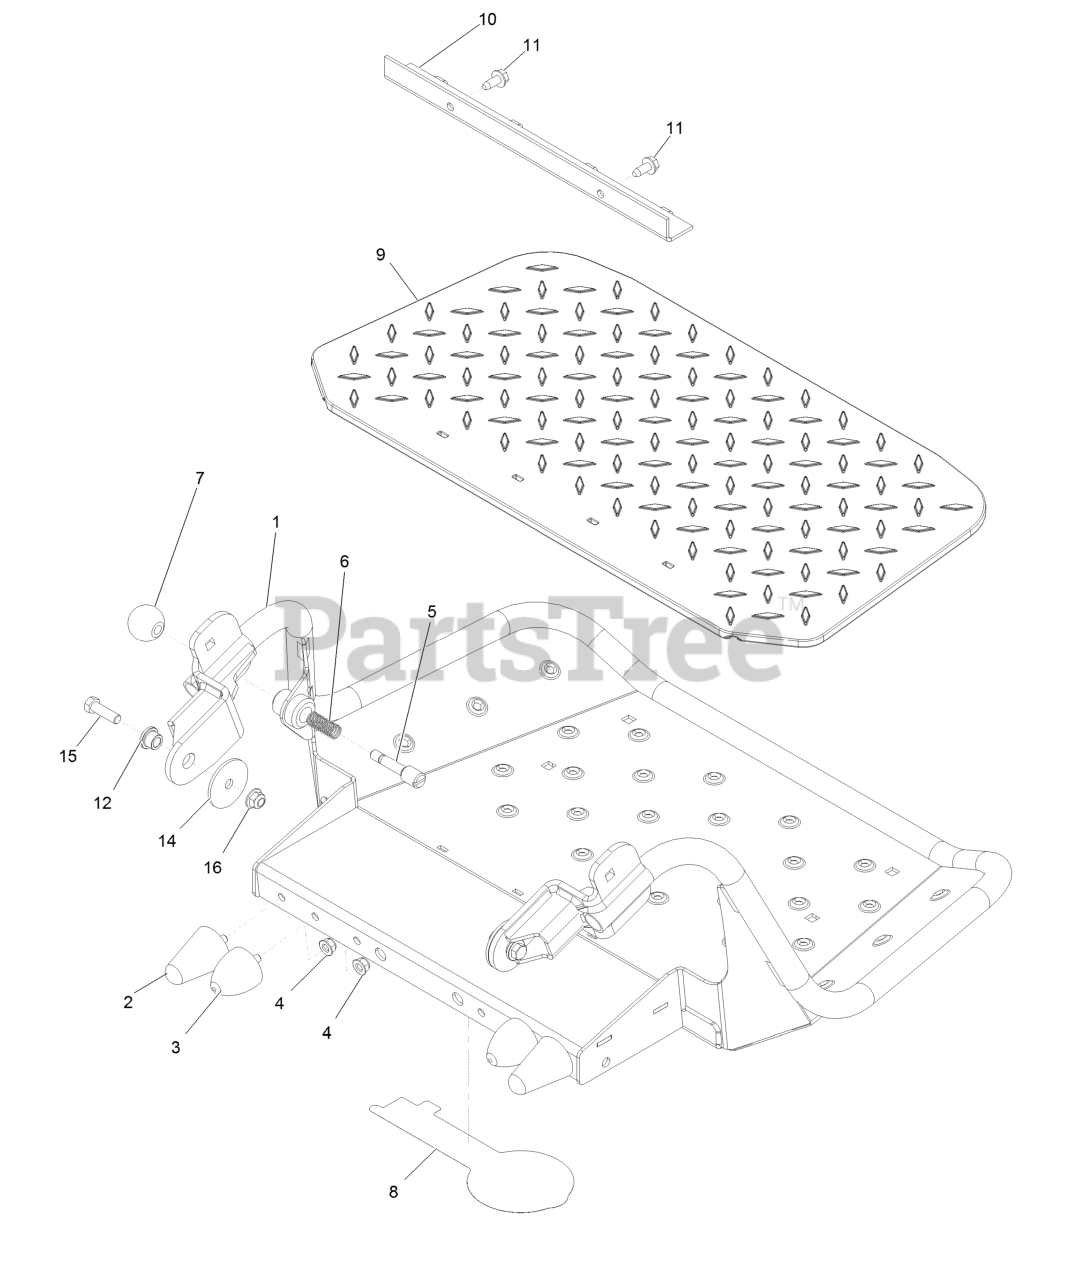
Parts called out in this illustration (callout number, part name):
1	Platform ASM [black]
2	Bumper-Rubber
3	Bumper-Rubber
4	Nut-Nyloc 5/16-18 Flg
5	Pin-Latch
7	Knob-Ball
8	Decal-Exmark Logo
9	Mat-Platform
10	Clamp-Shield
11	Screw-HWH 5/16-18 X 3/4 Tf
12	Bushing-Flanged
15	Screw-HH 3/8-16 X 1 1/4
16	Nut-Nyloc 3/8-16 Flg
